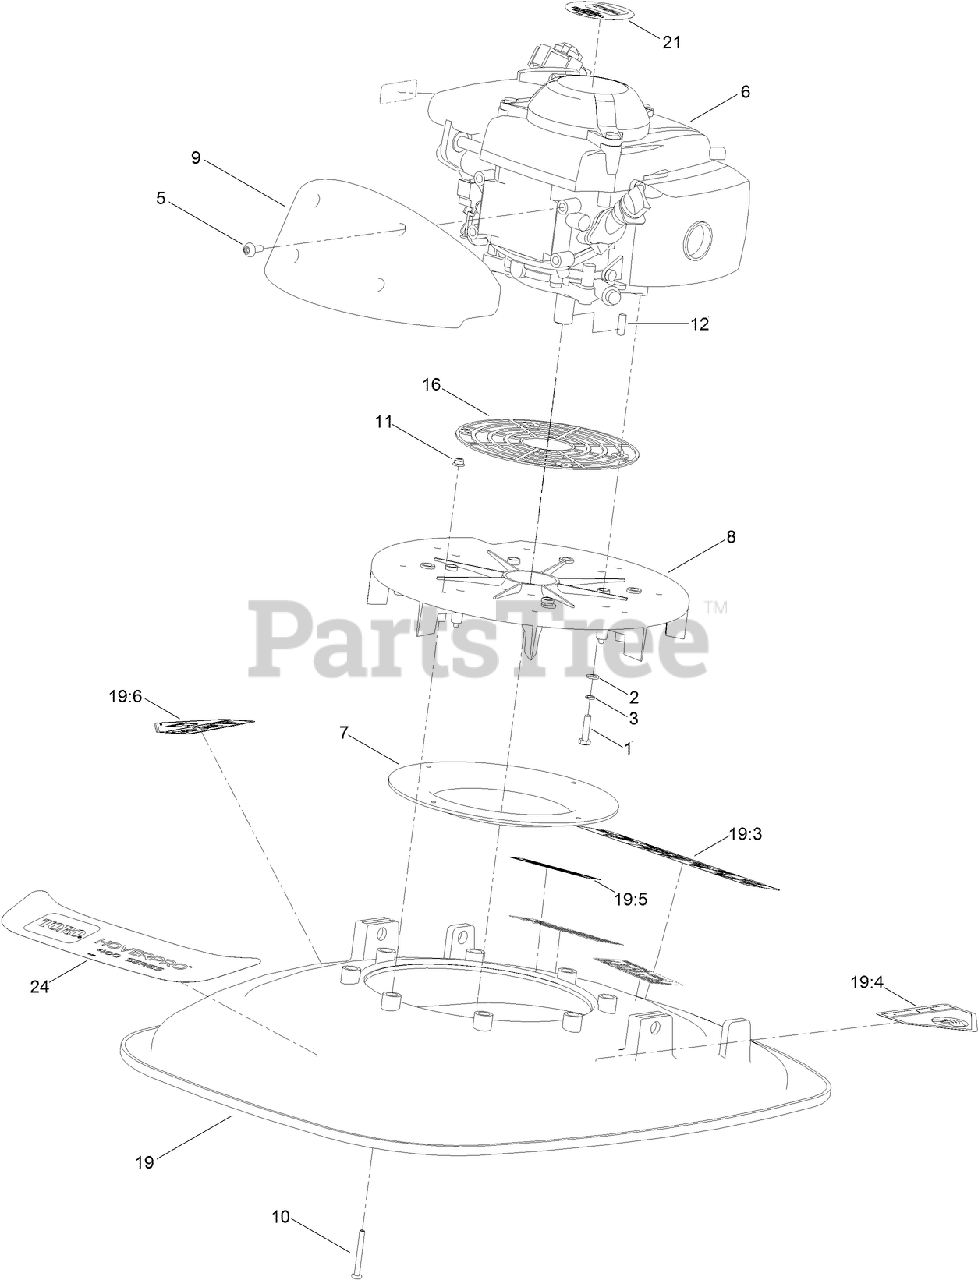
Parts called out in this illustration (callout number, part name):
1	SCREW-HH
2	WASHER-PLAIN
3	WASHER-SPRING
5	SCREW-SOC, HD
6	ENGINE-HONDA
7	BELL-MOUTH
8	PLATE-ENGINE
9	COVER-SUMP
10	SCREW-PPH
11	NUT-HHF, NY
12	KEY-DRIVE, SQUARE ENDED
16	SINK-HEAT
19:3	DECAL-WARNING
19:4	DECAL-DANGER
19:6	DECAL-DANGER
21	DECAL-ENGINE
24	DECAL-HOVER PRO
